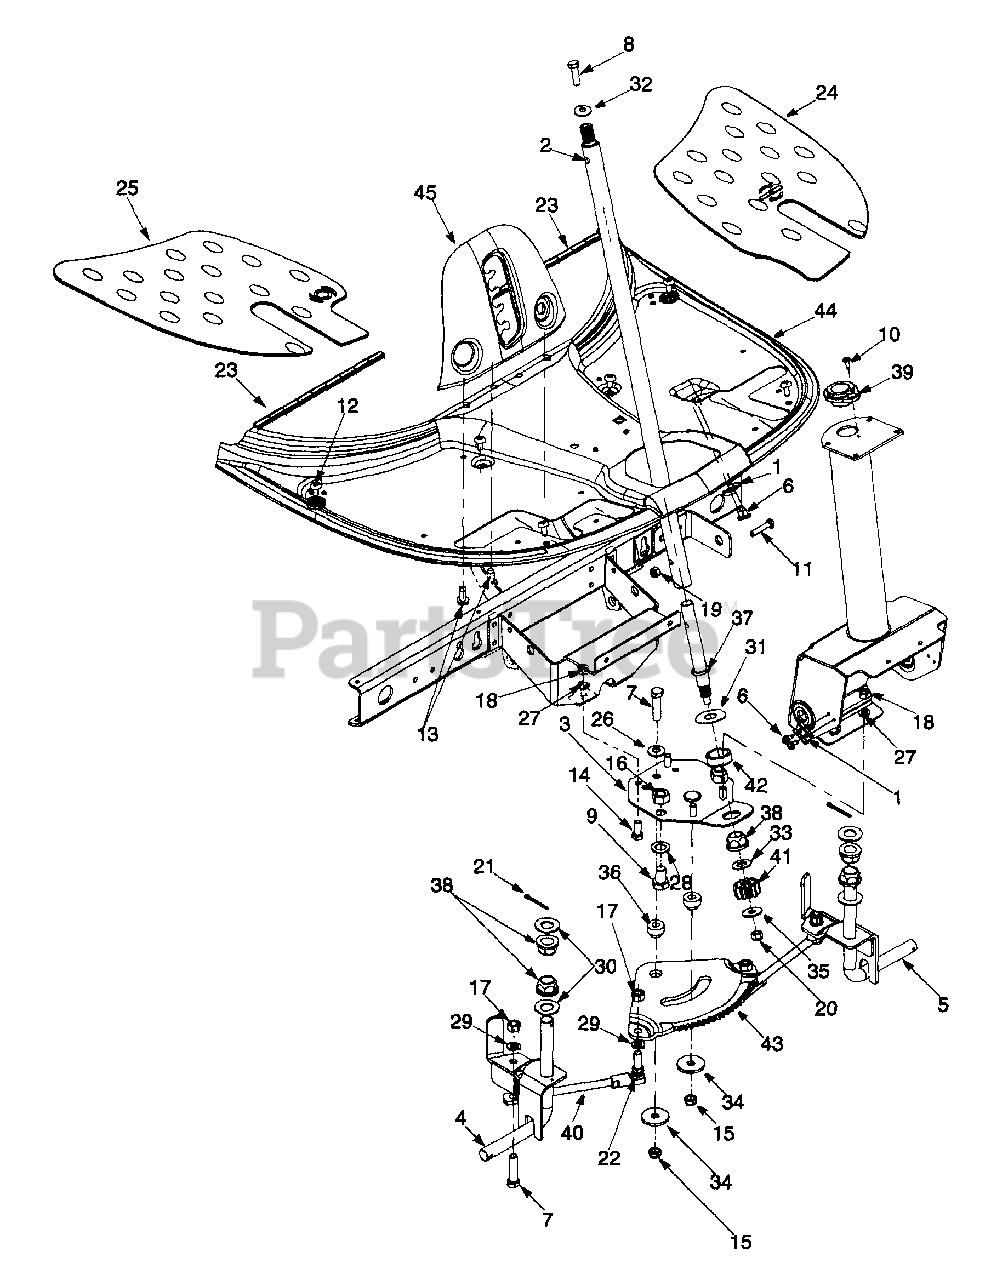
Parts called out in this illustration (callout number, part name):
1	Switch Plate
4	Front Axle Assembly: RH
5	Front Axle Assembly: LH
6	Hex Screw AB
7	Hex Screw 3/8-24 x 1.5" Gr.5 Special
8	Lock Screw 5/16-18 x 1.0" Gr.5
9	Hex Screw 1/2-13 x 0.75"
10	Oval Csunk Screw #10-16 x 0.625"
11	Hex Screw 1/4-20 x 1.25 Gr.5 Special
12	AB Screw 1/4-14 x 0.625"
13	Self-Tapping Screw 5/16-18 x 0.75"
14	Hex Screw 5/16-18 x 0.75"
15	Lock Nut 3/8-24
16	Hex Nut 1/2-13
17	Hex Nut
18	Hex Nut
19	Lock Nut 1/4-20
20	Lock Nut
21	Cotter Pin
22	Ball Joint
23	Trim Strip
24	Floor Pad: LH
25	Floor Pad: RH
26	Bell Washer
27	Lock Washer
28	Flat Washer
29	Lock Washer
30	Flat Washer
31	Flat Washer
32	Belleville Washer
33	Flat Washer
34	Flat Washer
35	Flat Washer
36	Spacer
37	Steering Adapter
38	Hex Flange Bearing
39	Bearing: Steering Column
40	Tie Rod
41	Pinion Gear
42	Spacer
43	Gear: Steering Segment
